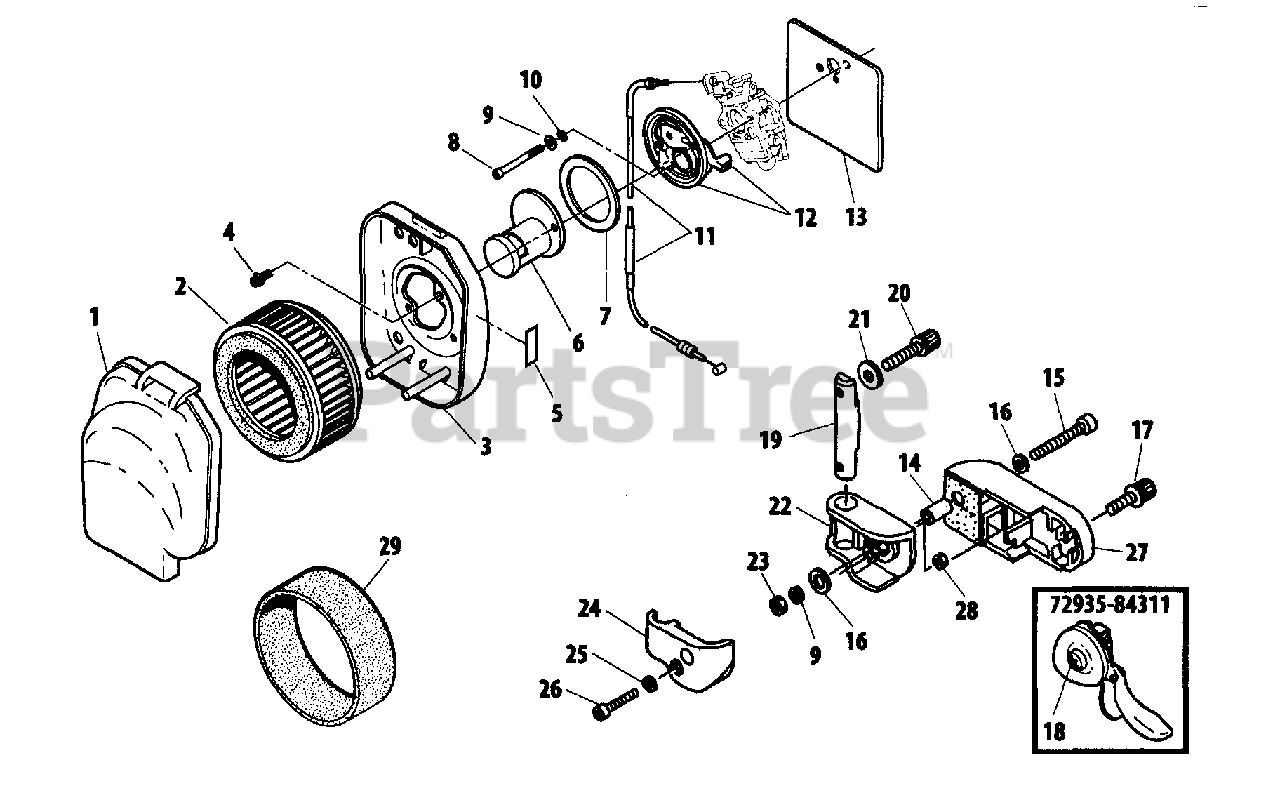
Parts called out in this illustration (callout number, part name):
1	COVER, AIR FILTER
2	FILTER, AIR
3	CASE, AIR FILTER
4	SCREW - 4X14
5	LABEL - CHOKE
6	ADAPTOR, INTAKE
7	GASKET
8	SCREW - 5X60
9	LOCKWASHER - 5
10	WASHER - 5
11	CABLE, THROTTLE
12	CHOKE ASSY
13	GASKET, INTAKE
14	COLLAR
15	SCREW - 5X25
16	WASHER
17	SCREW - 6X16
18	SCREW
20	SCREW - 6X16
24	COVER
25	WASHER - 4
26	SCREW - 4X20
27	BRACKET
28	NUT - 4
29	PRE-FILTER
72935-84311	THROTTLE LEVER ASSY
